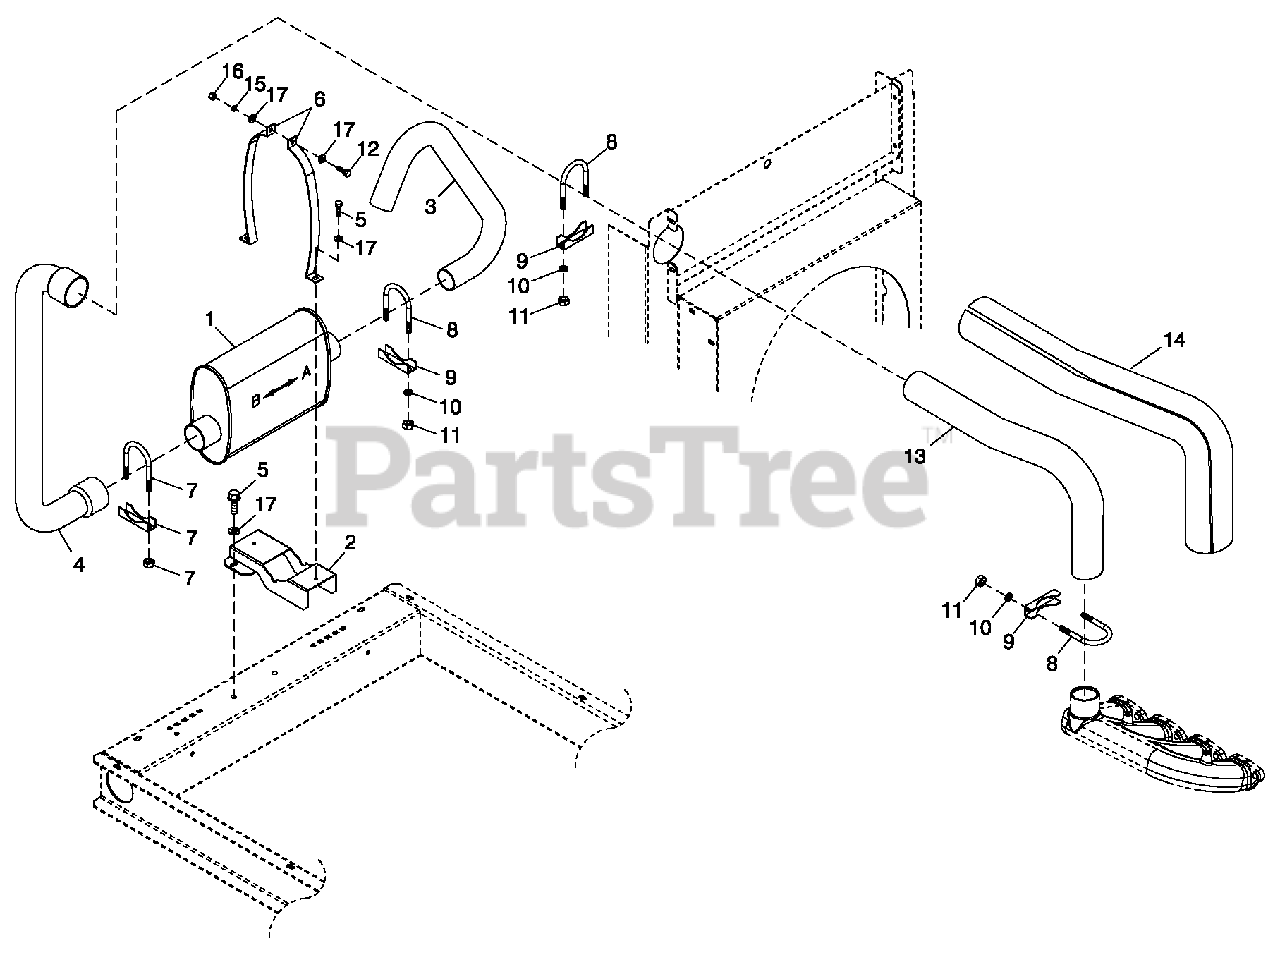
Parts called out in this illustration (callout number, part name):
1	MUFFLER C1
2	MUFFLER SADDLE
3	PIPE EXHAUST OUTLET
4	PIPE EXH INLET MUFLR SIDE 1.5L
5	SCREW HWHTF M6_1.0 X 16
6	MUFFLER STRAP
7	BOLT U 5/16_18 X 2_1/4
8	BOLT U 5/16_18 X 2.09
9	SADDLE 2 INCH
10	WASHER LOCK M8_5/16
11	NUT HEX 5/16_18 STEEL
12	SCREW HHC M6_1.0 X 30 G8.8
13	EXHAUST PIPE 1.6L
14	EXHAUST BLANKET 600MM LONG
15	WASHER LOCK M6_1/4
16	NUT HEX M6 X 1.0 G8 YEL CHR
17	WASHER FLAT 1/4_M6 ZINC
